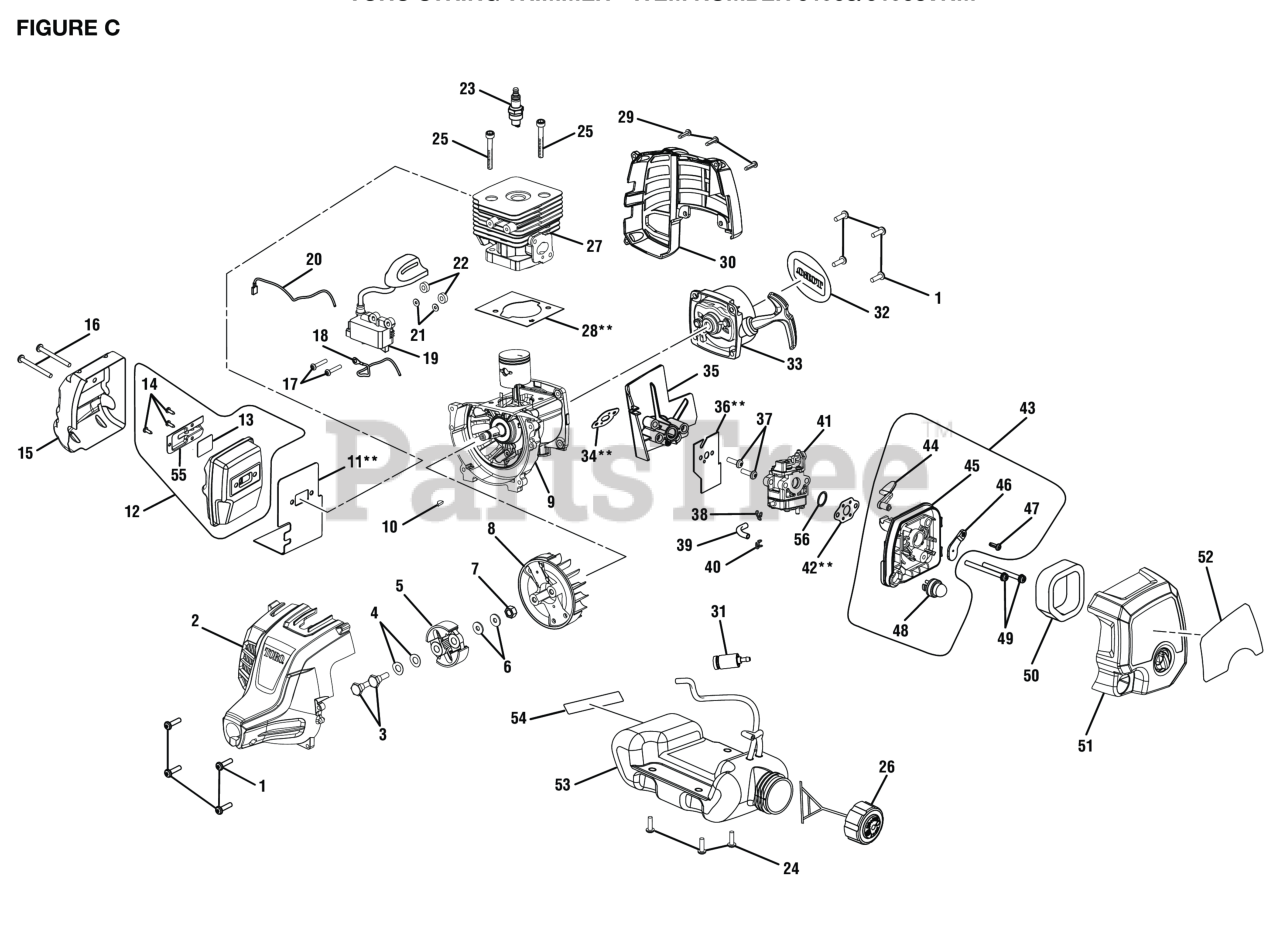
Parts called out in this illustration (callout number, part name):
1	Cap Screw w/Washer (M5 x 16 mm, T25 Torx Soc. Hd.)
2	Front Housing Assembly
3	Clutch Shoulder Bolt (M6 x 22.5 mm, Hex Hd.)
4	Washer (Curved)
5	Clutch Assembly
6	Washer (ID6 x OD15 x 1.2t)
7	Flange Nut (M8, Flywheel)
9	Crankcase Assembly.
10	WOODRUFF KEY (10 mm X 3 mm)
11	Muffler Gasket
12	Muffler Assembly
13	SCREEN
14	Screw (6-20 x 1/4 in., T20 Torx Pan Hd. S.T.)
15	HEAT SHIELD
16	Screw (M5 x 50 mm, Torx Slotted Recessed Pan Hd.)
17	Screw (M4 x 22 mm, T20 Torx Slotted Recessed Pan Hd.)
18	Lead Wire Assembly, Red
19	Coil Boot Assembly
20	Lead Wire Assembly, Black
21	Flat Washer (OD10 x ID42 x 1t)
22	Phenolic Spacer (Ignition Module)
23	SPARK PLUG (CHAMPION RCJ4)
24	Shoulder Screw w/Washer (M4 x 14 mm, T25 Torx Truss Hd.)
25	Screw (M5 x 22 mm, T25 Torx Soc. Hd.)
26	Fuel Cap Assembly
28	Gasket
29	Screw (M4 x 18 mm, T20 Torx Pan Hd. S.T.)
30	Rear Engine Housing
31	Fuel Filter
32	Logo Label (Rear)
33	Starter Recoil & Starter Cup Assembly
34	Heat Dam Insulator
36	Gasket
37	Screw w/Washers (M5 x 30 mm, T25 Torx Pan Hd.)
38	Clip-hose (Id 4.9)
39	Fuel Line (45 mm)
40	CLIP-HOSE (ID 4.9)
41	CARBURETOR ASSEMBLY
42	Carburetor Gasket
43	Filter Housing Assembly
44	CHOKE LEVER
45	CARBURETOR PLATE
46	Screw (M4 x 12 mm, T20 Torx Pan Hd. S.T.)
47	Screw (M4 x 12 mm, Slotted Recessed Pan Hd.)
48	Primer Bulb Assembly
49	Screw (M5 x 44 mm,T25 Torx Hd. Carburetor)
50	Air Filter (Element)
51	Airbox Cover Assembly w/Label
52	Starting Instructions Label
53	Fuel Tank & Cap Assembly
54	Combustion Warning Label
55	Trimmer Outlet
